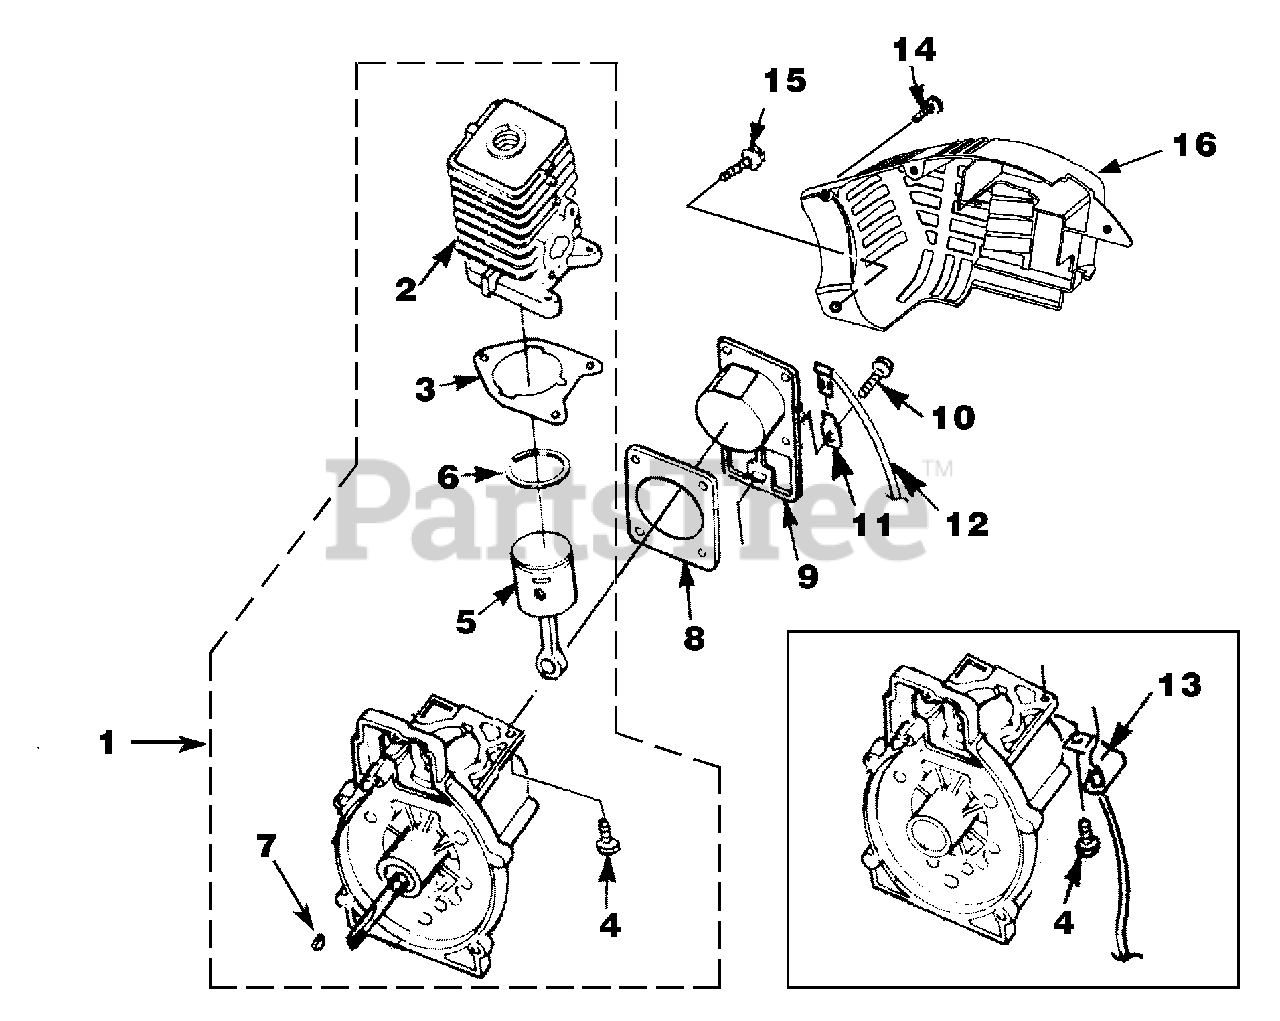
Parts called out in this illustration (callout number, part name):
1	SHORT BLOCK W/Rotor (30cc)
1	SHORT BLOCK W/Rotor (25cc)
2	30 CC CYLINDER KIT
2	25 CC CYLINDER KIT
3	GASKET-Cylinder
4	SCREW, SEMS (12-24 x 3/4)
5	30 CC PISTON & ROD
5	25 CC PISTON & ROD
6	RING-Piston
7	KEY-Woodruff
8	GASKET-Crankcase
9	CRANKCASE COVER-Stamped Steel
9	CRANKCASE COVER-Aluminum
10	SCREW, SEMS (10-24 x .56)
10	SCREW, SEMS (10-24 x .810)
11	TAB-Male
12	CABLE-Throttle w/Ignition Leads
13	CABLE BRACKET
14	SCREW-Thread Form. (#8 X 1/2")
15	SCREW-Thread Form. (#10 X 3/4")
16	SHROUD
